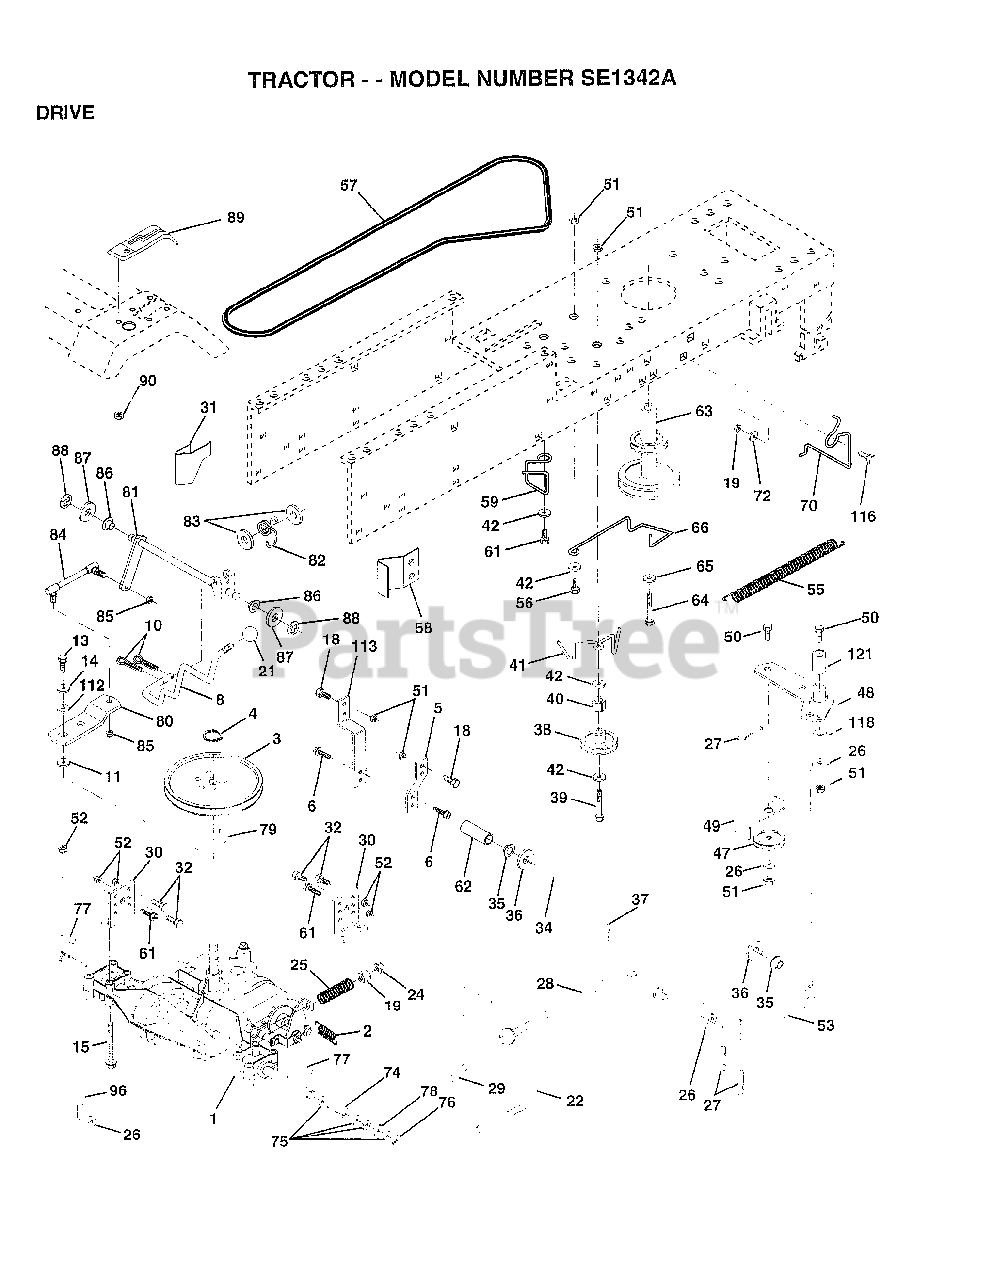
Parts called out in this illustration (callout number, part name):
2	SPRING.BRAKE.RETU
3	PULLEY TRANS
5	STRAP TORQUE
6	SCREW
8	ROD SHIFT FEND LT
10	PIN COTTER 1/8
11	WASH-SHFT PLT LT
13	BOLT.1/4-28.W/PAT
14	LOCKWASHER
15	BOLT.HX.FLG.5/16
18	BOLT
19	NUT
21	KNOB T (1/2-HOLE)
22	BRAKE ROD
24	NUT
25	SPRING ROD LT
26	WASHER
27	COTTER PIN
28	ROD.BRAKE.PARK.LT
29	PLUNGER CAP T
30	TRANSAXLE MTG BKT
31	"KEEPER,BELT LH T"
32	BOLT
34	SHAFT ASM-PEDAL F
35	NYLON BEARING
36	WASHER LT
38	PULLEY.IDLER.FLAT
39	BOLT
40	SPACER T
42	WASHER
48	BELLCRANK ASM
49	RETAIN BELT
53	"LINK, CLUTCH T"
55	"SPRING, RETURN LT"
58	"KEEPER,BELT RH T"
59	KEEPER BELT CNTSP
61	SCREW
62	PEDAL COVER T
63	PULLEY.ENGINE
64	BOLT
65	LOCKWASHER
66	KEEPER-BELT
70	KEEPER BELT ENG
72	WASHER
74	SPACER AXLE
75	WASHER
76	E-RING LT
77	SQUARE KEY
78	WASHER
80	"ARM.SHIFT.20""TIRE"
81	SHAFT.CROS.P930.
82	"SPRING,TORSION"
83	WASHER
84	"ROD.TIE.20""P930LT"
85	NUT.CNT.LOCK.1/4
86	BUSHING
87	WASHER D
88	KLIP RING
90	NUT
112	WASHER LT
113	"STRAP,TORQUE"
116	BOLT RDHD 3/8-16
118	SPACER BELLCRANK
121	NYLINER-CLUTCHING
